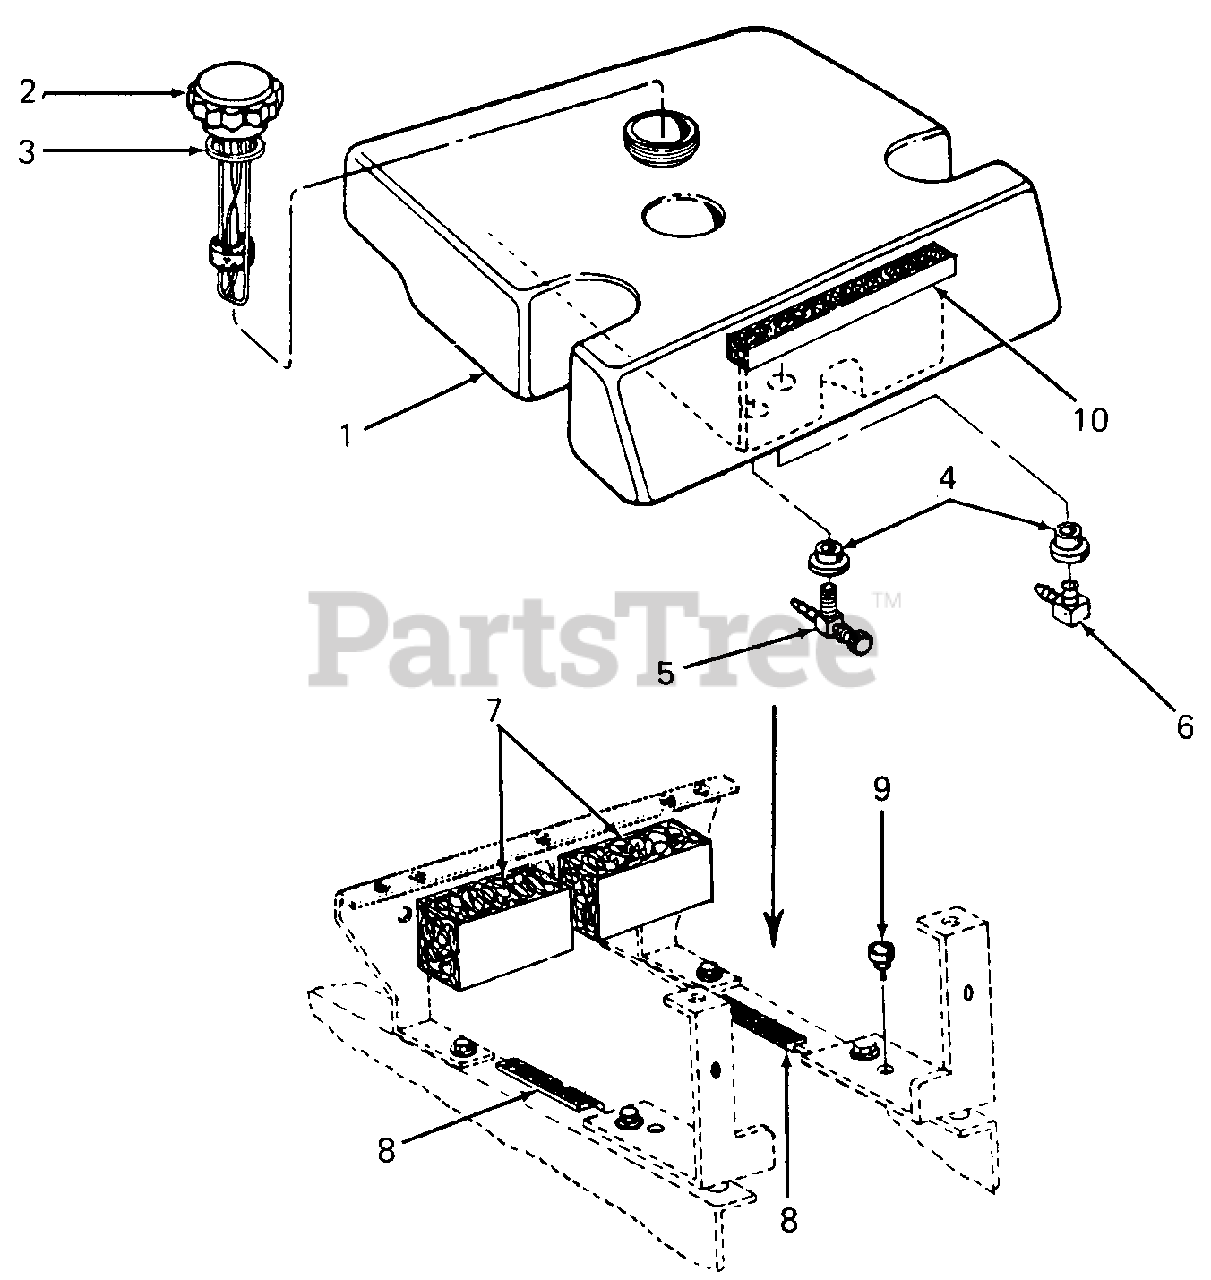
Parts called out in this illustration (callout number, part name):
1	Tank Assy, Fuel
2	Cap w/Gauge, Fuel
3	Gasket, Fuel Tank Cap
4	Bushing
5	Valve w/Screen, Shut-Off
6	Fitting, Fuel Line
7	Strip, Foam Gasket Sealing, 3 in. Lg
8	Strip, Trim, 4 in. Lg
9	Bumper, Rubber
10	Strip, Foam Gasket Sealing, 12 in. Lg
